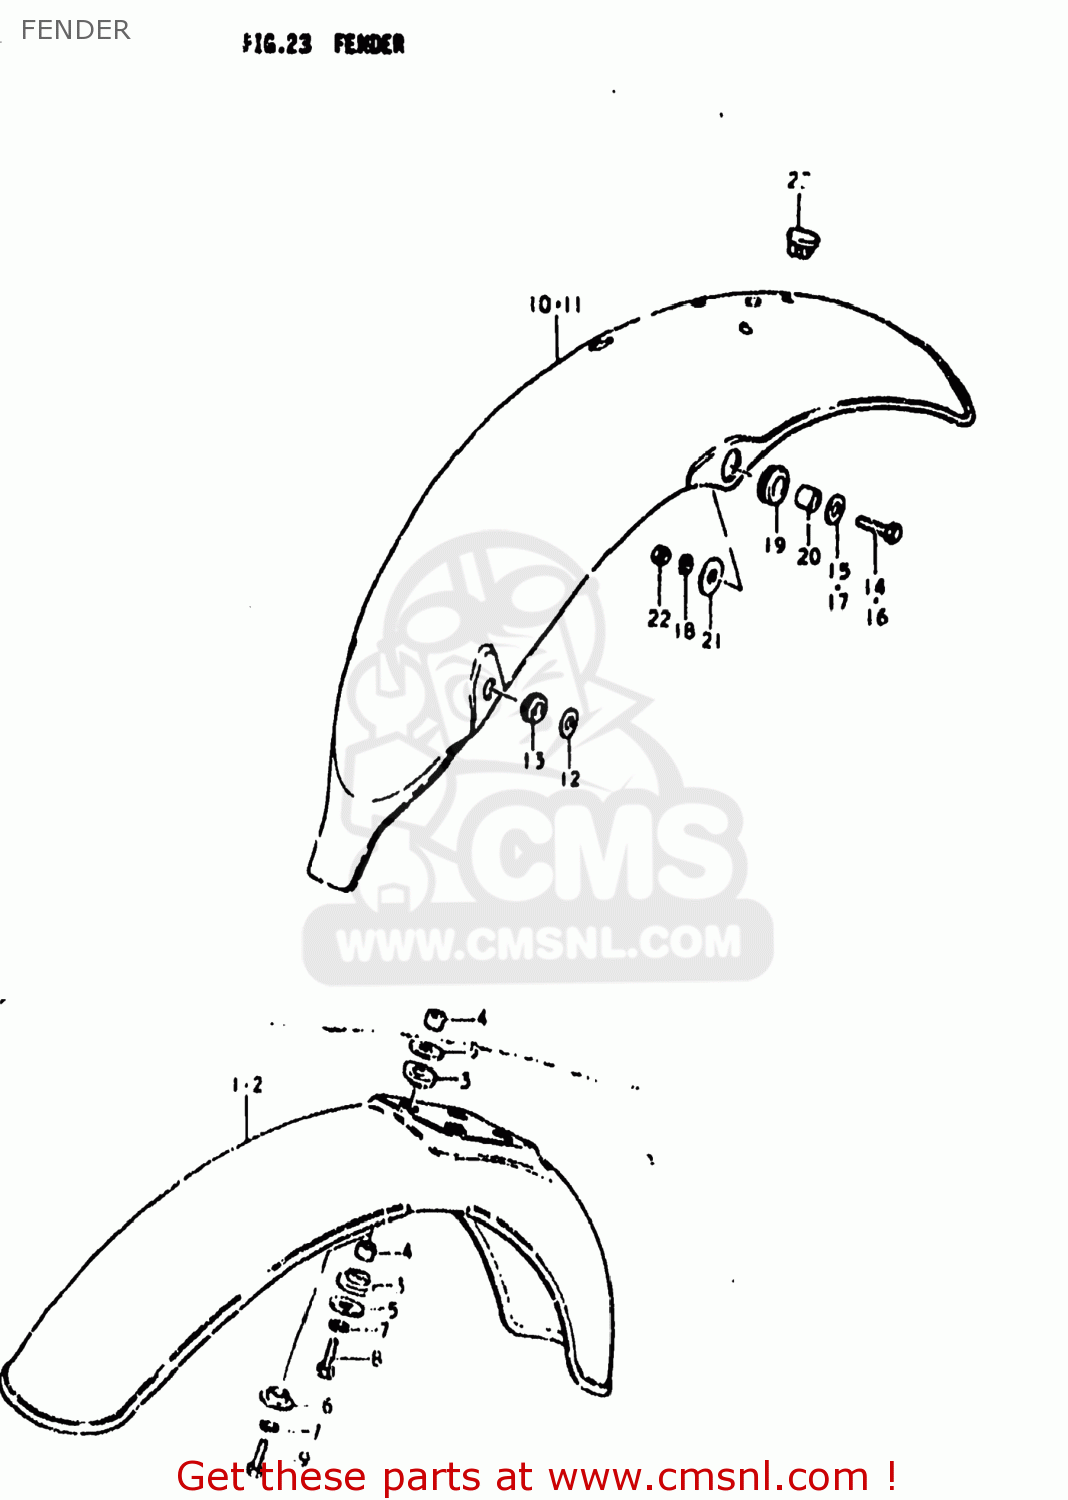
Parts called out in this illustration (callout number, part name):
1	FENDER,FRONT
2	FENDER,FRONT
3	CUSHION
4	SPACER (6.8X10X10)
5	WASHER (6.5X20X1.2)
6	SPACER
7	LOCK WASHER
8	BOLT
9	BOLT, UPPER
10	FENDER,REAR
11	FENDER,REAR
12	WASHER
13	CUSHION
14	BOLT,8X75
15	WASHER
16	BOLT
17	WASHER
18	LOCK WASHER
19	CUSHION
20	SPACER (8.2X12X7.5)
21	WASHER(8.5X26X1.2)
22	NUT
23	CUSHION
